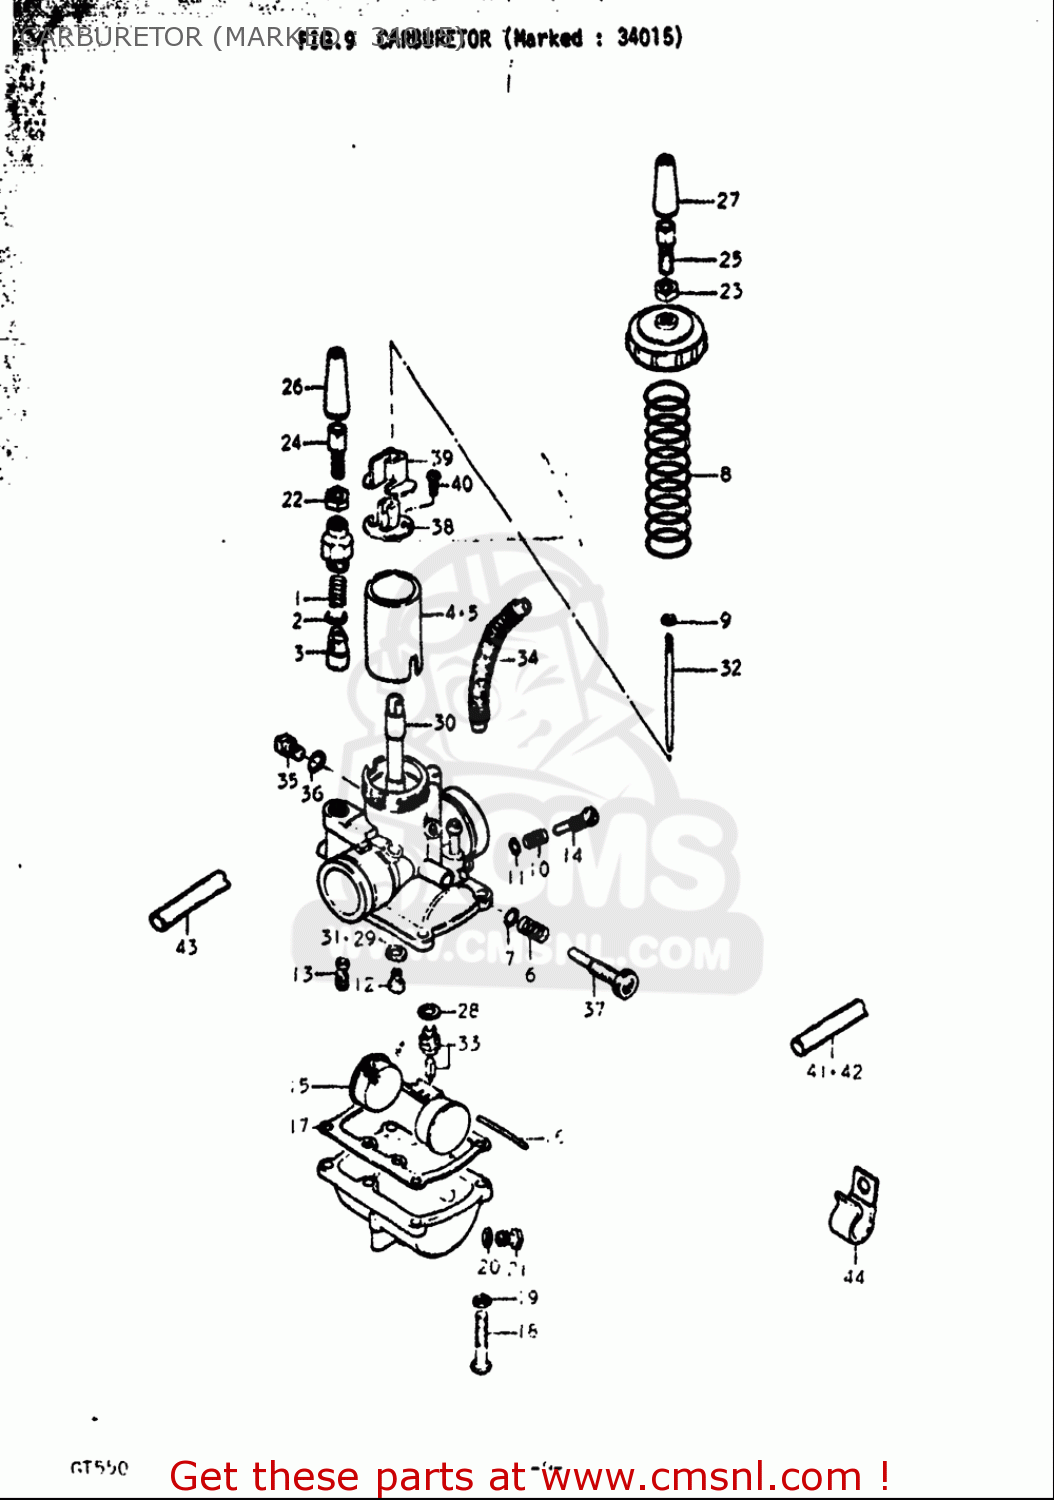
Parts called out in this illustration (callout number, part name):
1	SPRING
3	PLUNGER,STARTER
6	SPRING,THROTTLE SCREW
7	O RING
9	CLIP
10	SPRING
11	O RING
12	JET,MAIN(95)
13	JET,PILOT(25)
14	SCREW,PILOT AIR
15	FLOAT
16	PIN,FLOAT
17	GASKET,FLOAT CAHMBER (NAS)
18	SCREW 4X16
19	WASHER,LOCK
20	GASKET,DRAIN,PLUG (NAS)
21	PLUG
22	NUT
24	ADJUSTER,CABLE
26	CAP,RUBBER
28	GASKET,VALVE SEAT (NAS)
29	WASHER
33	VALVE ASSY,NEEDLE
35	BOLT
36	GASKET,THRO VALVE INSPECTION (NAS)
38	CONNECTOR
40	SCREW
